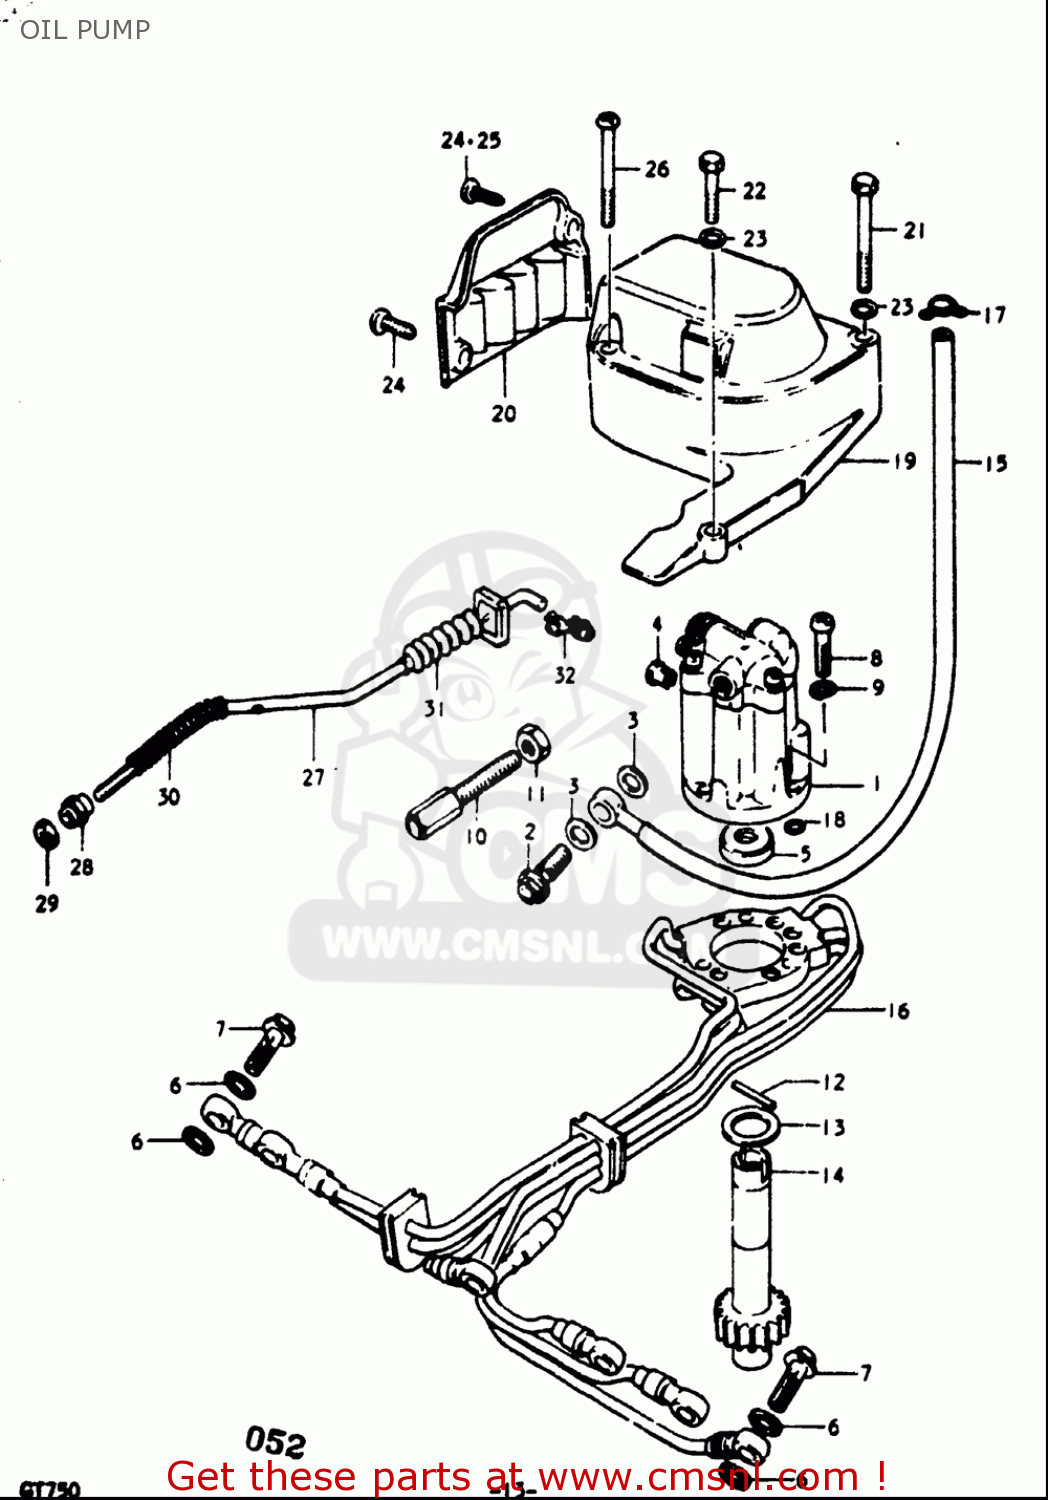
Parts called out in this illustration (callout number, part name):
2	UNION BOLT
3	GASKET(6.2X11X1).2 (NAS)
4	TERMINAL,CABLE
5	SEAL,OIL(8X16X4)
6	GASKET(6.2X11X1).2 (NAS)
7	UNION BOLT
8	SCREW
9	WASHER,LOCK
10	BOLT
11	NUT
12	PIN(3X13.8)
13	SHIM(14X22X1)
17	CLIP
18	O RING(D:1.9,ID:3.8)
21	BOLT 5X45
22	BOLT 5X20
23	WASHER
24	SCREW
26	SCREW
27	ROD,OIL PUMP CONTROL
28	NUT
29	NUT
31	BOOT,OIL PUMP CONTROL ROD
32	HOLDER,OIL PUMP ROD
